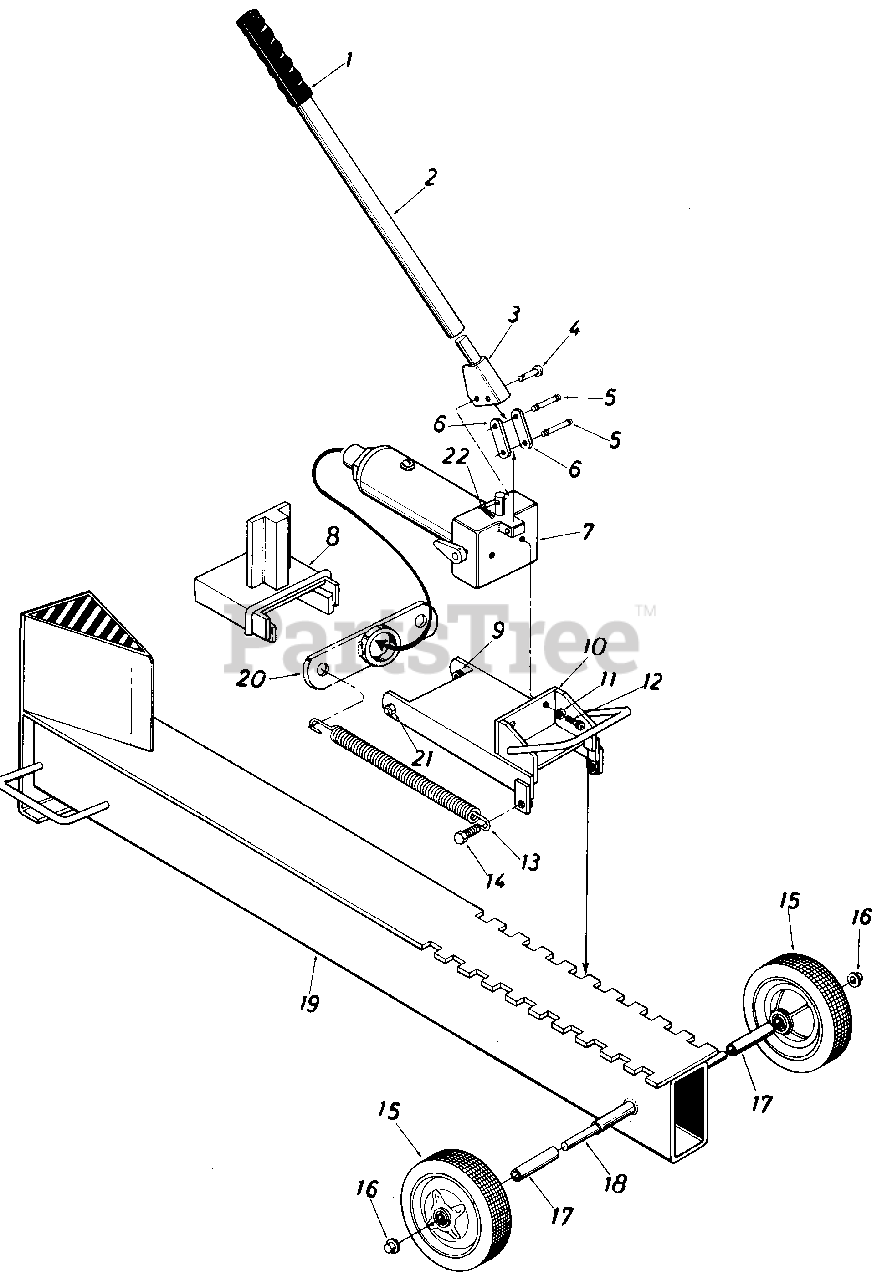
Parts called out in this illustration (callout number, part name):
1	Handle Grip
2	Handle 3/8" Dia. Rod
3	Handle Socket
4	Clevis Pin
5	Pin & Ring Assembly
7	Hydraulic Pump & Cylinder
8	Push Plate Ass'y.
9	Socket Hd. Bolt 1/2- 13 x .75" Lg.
10	Cylinder Mounting
11	L.-Wash. 3/8" I.D.*
12	Socket Hd. Bolt 3/8- 16 x .75" Lg.
13	Extension Spring .75" O.D. x 10.75" Lg.
14	Hex L.-Bolt 3/8-16 x 75" Lg
15	Wheel 7.0" x 1.75"
16	1/2" Push Cap
17	Spacer
18	Axle 1/2" Dia. x 12" Lg.
19	Tube and Rail Ass y.
20	Cyl. Return Ass y.
21	Hex Cent. L.-Nut 1/2- 13 Thd.
22	Hair Pin Cotter
